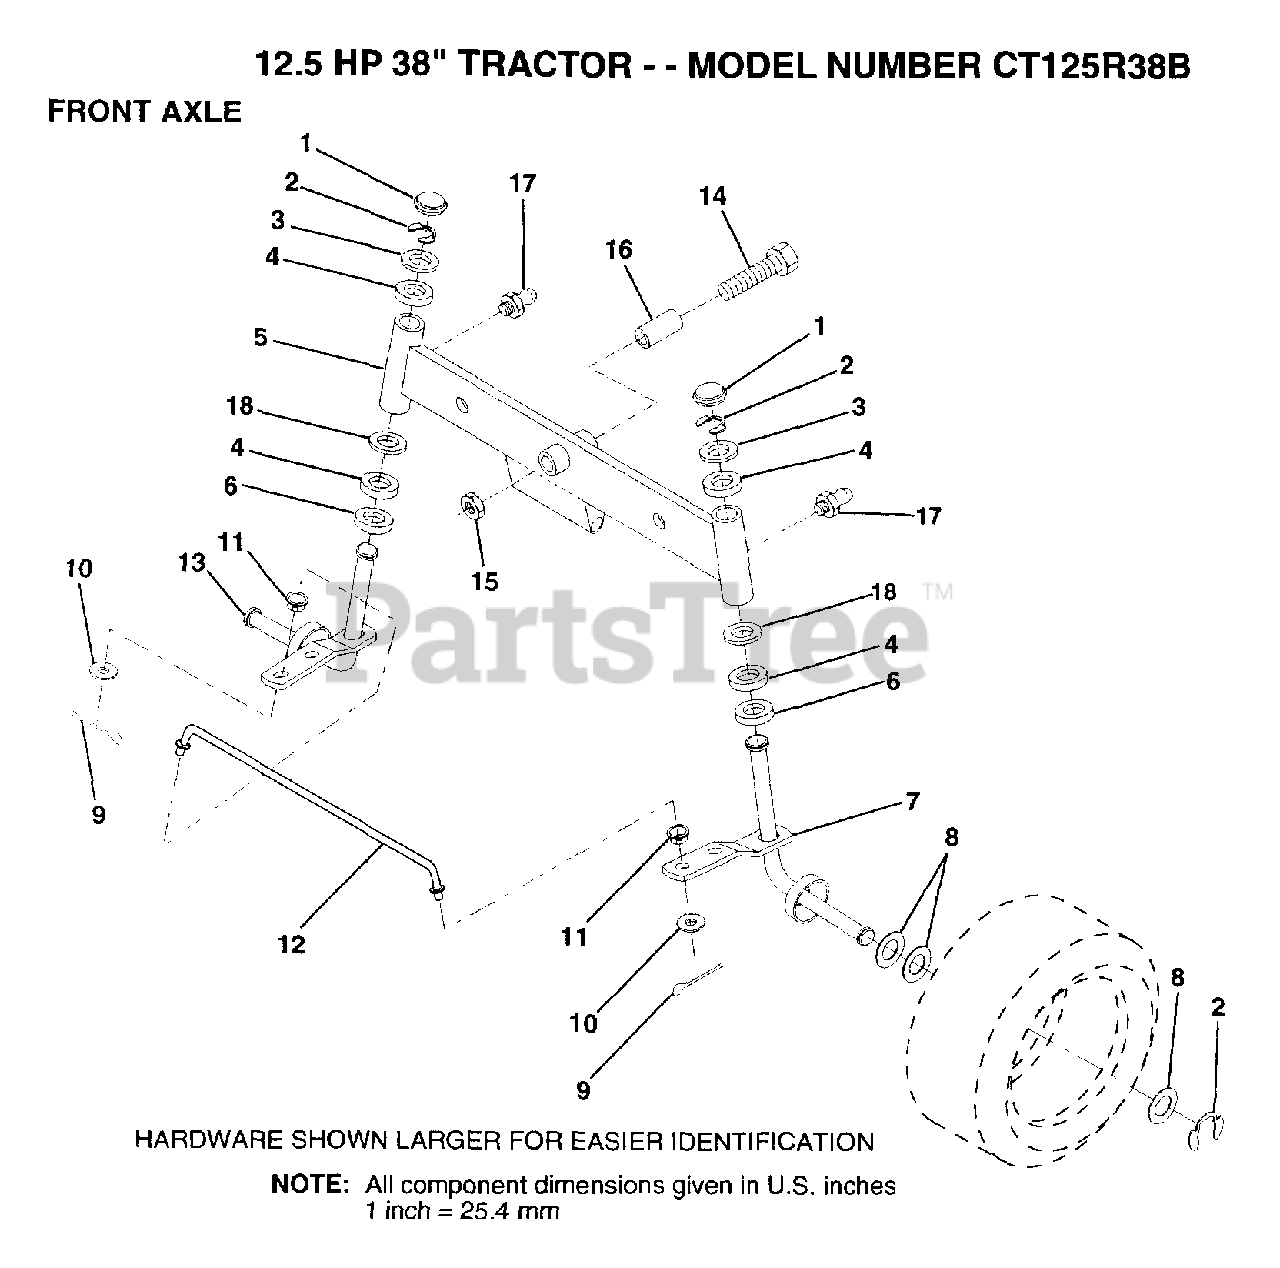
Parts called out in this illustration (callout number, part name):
1	CAP
2	RING
3	WASHER
4	COL. SRTG. BEAR.
6	WASHER .T
7	SPINDLE ASM RH
8	WASHER
9	COTTER PIN
10	WASHER
11	BUSHING.DRAGLINK
12	TIE ROD
13	SPINDLE ASM LH
14	BOLT HEX 5/8-11
15	"NUT-LOC,FLANGE LT"
16	SPACER, BEARING, FRONT AXLE
17	ZERK M
18	WASHER
